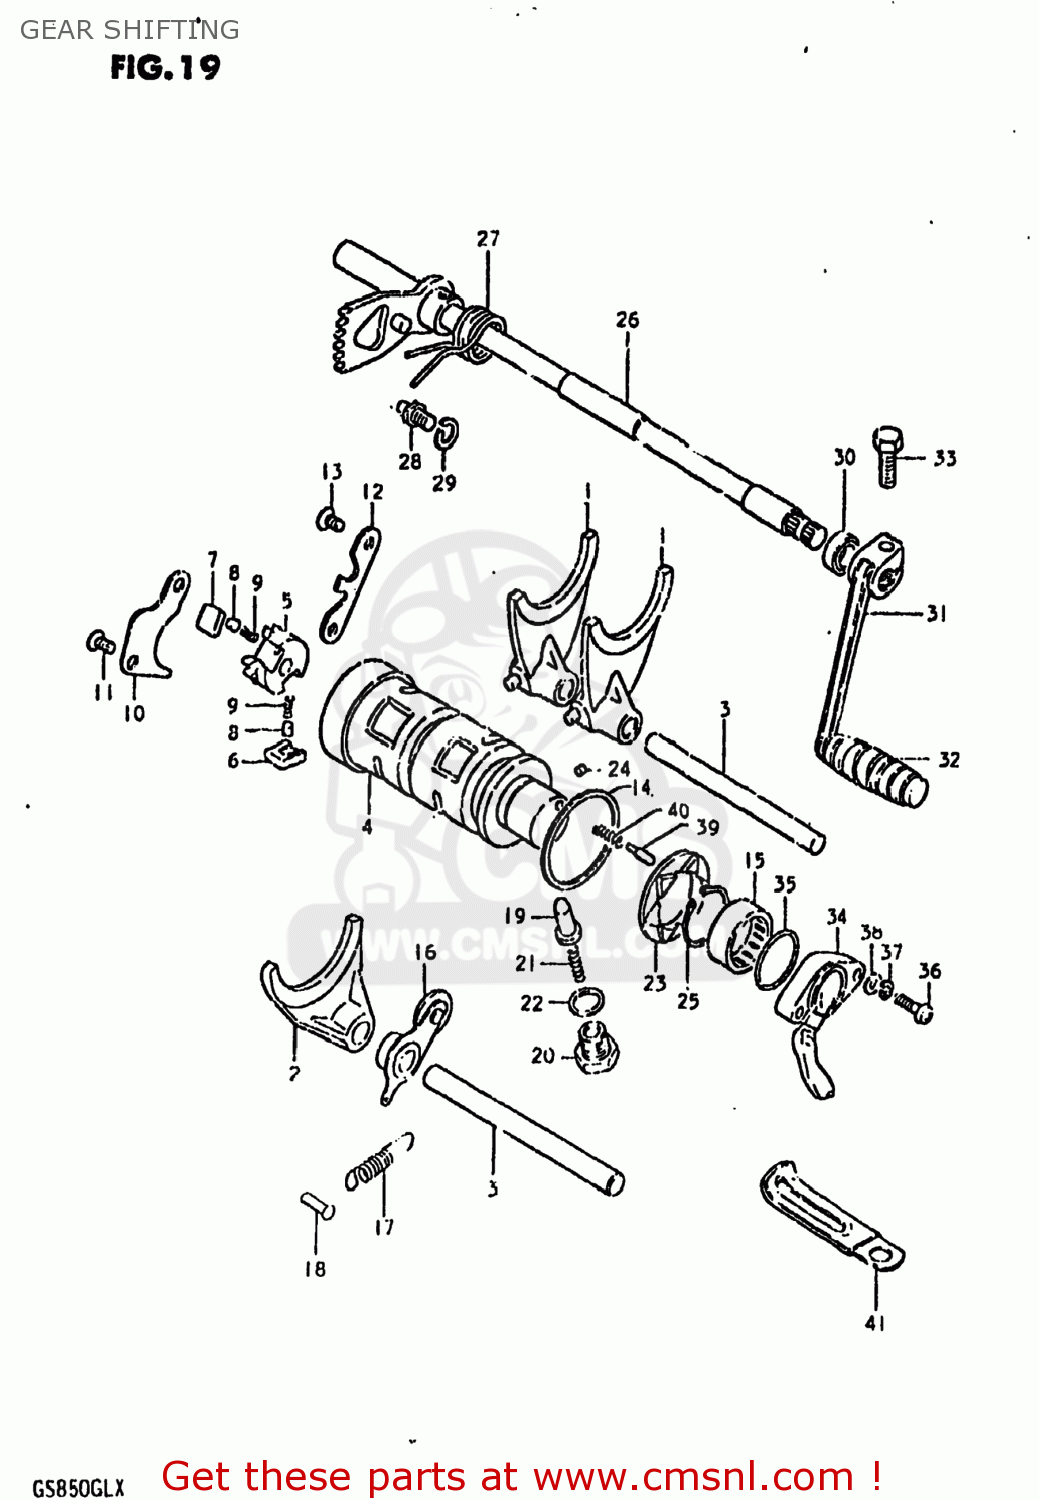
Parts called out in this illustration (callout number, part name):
1	FORK,GEAR SHIFT NO.1
2	FORK,GEAR SHIFT NO.3
3	SHAFT,GEAR SHIFT FORK
4	CAM,GEAR SHIFT
5	SHIFTER,GEAR SHIFT CAM
6	PAWL,GEAR SHIFT NO.1
7	PAWL,GEAR SHIFT NO.2
8	PIN(5X8)
9	SPRING
10	LIFTER,GEAR SHIFT PAWL
11	SCREW
12	GUIDE,GEAR SHIFT CAM
13	SCREW
14	WASHER(40X45X1)
15	BEARING
16	STOPPER,GEAR SHIFTING
17	SPRING
18	RIVET
19	STOPPER,GEAR SHIFT CAM NO.2
20	HOLDER,GEAR SHIFT CAM STOP SPR
21	SPRING
22	GASKET(14X19.2X2) (NAS)
23	PLATE,GEAR SHIFT CAM STOPPER
24	PIN 4X6
25	CIRCLIP
26	SHAFT,GEAR SHIFT
27	SPRING
28	STOPPER,GEAR SHIFT CAM
29	WASHER
30	OIL SEAL
31	LEVER ASSEMBLY,GEAR SHIFTING
32	RUBBER,GEAR SHIFT PEDAL
33	BOLT
34	TERMINAL BASE ASSY,GEAR SHIFT
35	O-RING (D:2.4 ID:26.2)
36	SCREW 5X20
37	LOCK WASHER
38	WASHER
39	PIN(5X15.5)
40	SPRING
41	CLAMP
